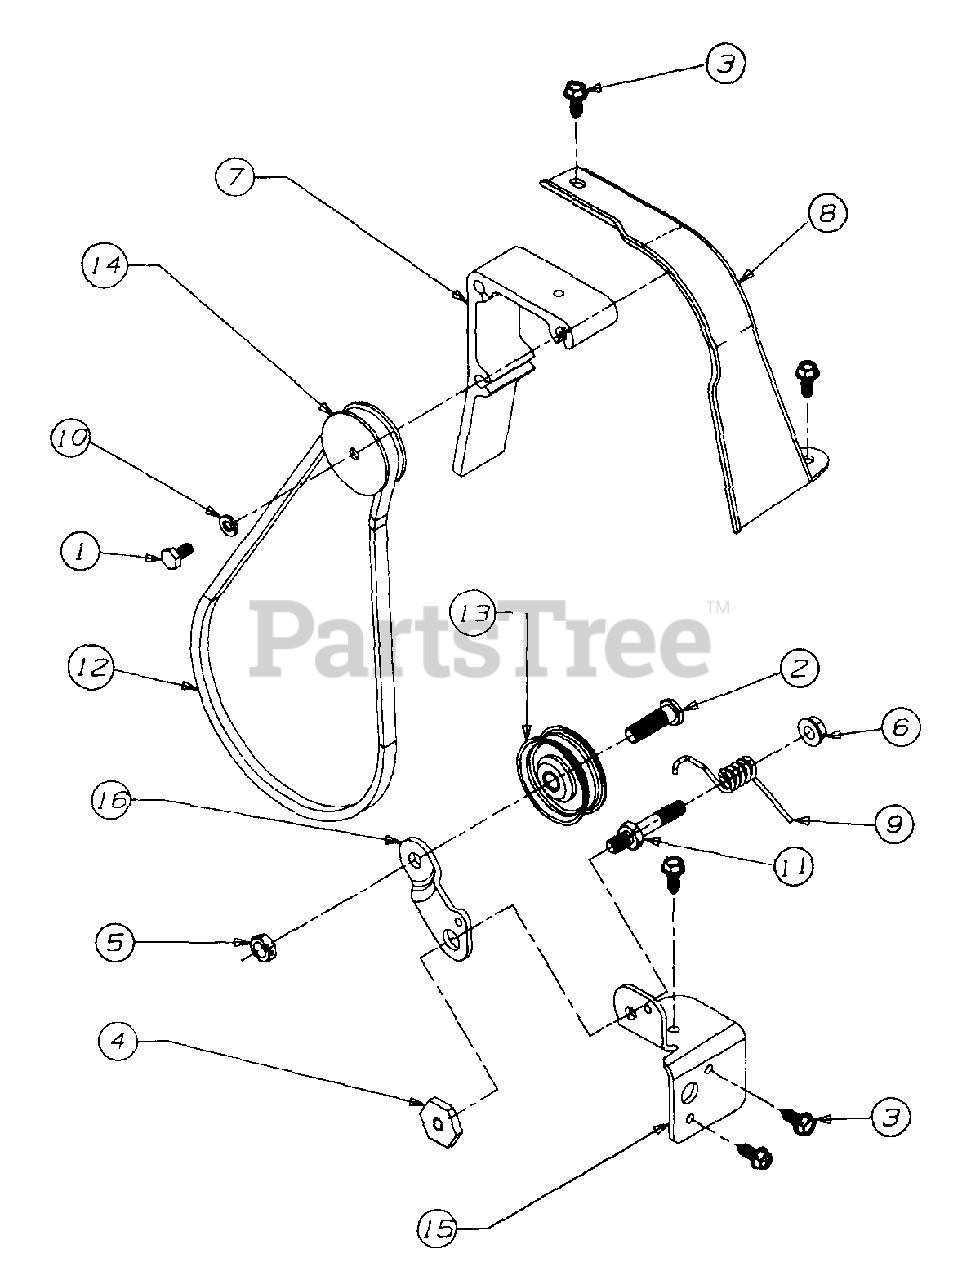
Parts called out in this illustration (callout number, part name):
1	SCREW-HEX
2	SCREW-HEX
3	SCREW-HEX
4	NUT-HEX SHOULDER
5	NUT-HEX LOCK
6	NUT-HEX LOCK FLANGE
7	ADAPTER-MOUNTING
10	WASHER-LOCK
11	BOLT-IDLER
12	V BELT
13	IDLER-FLAT
14	PULLEY
